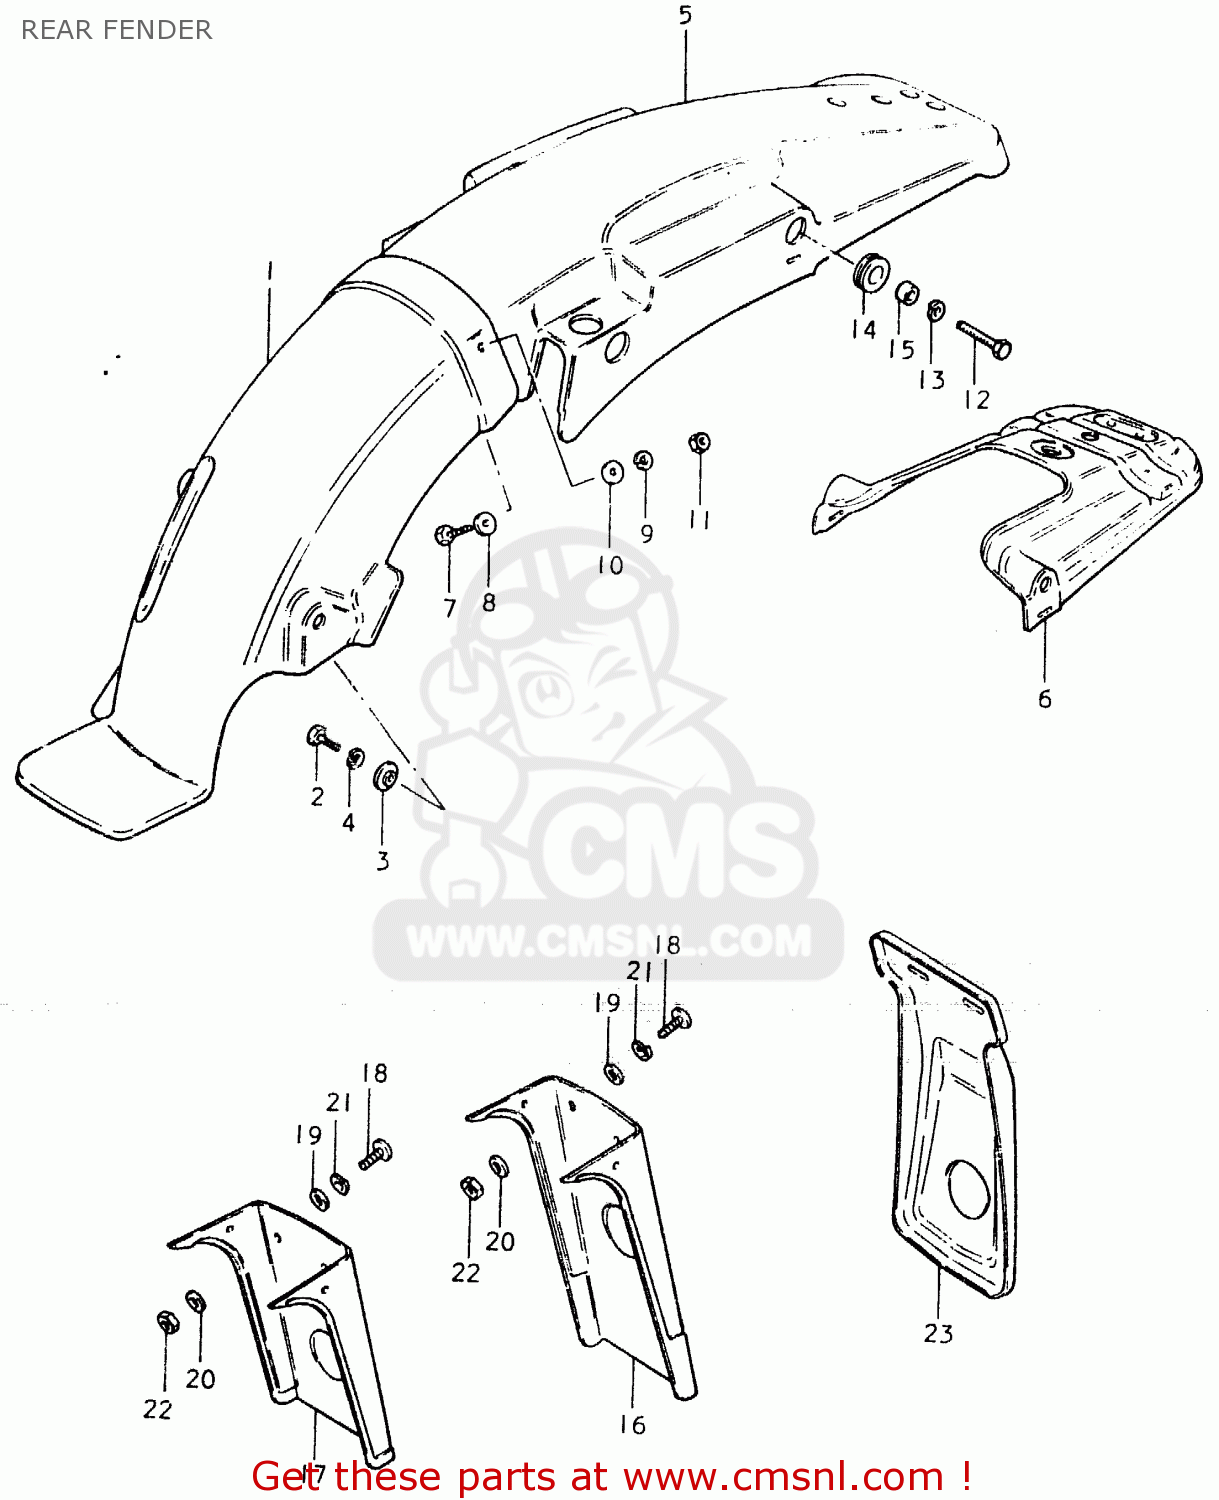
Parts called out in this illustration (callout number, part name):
1	BODY,REAR FENDER,FRONT
2	BOLT, UPPER
3	WASHER
4	LOCK WASHER
5	FENDER, REAR
6	REINFORCEMENT
7	BOLT
8	WASHER (5.5X16X1.2)
9	LOCK WASHER
10	WASHER(5.2X16X1)
11	NUT
12	BOLT (8X30)
13	LOCK WASHER
14	CUSHION
15	SPACER (8.2X12X7.5)
16	MUD FLAP
17	MUD FLAP
18	SCREW
19	WASHER (6.5X18X1.6)
20	WASHER
21	LOCK WASHER
22	NUT
23	FLAP,RR FENDER MUD
